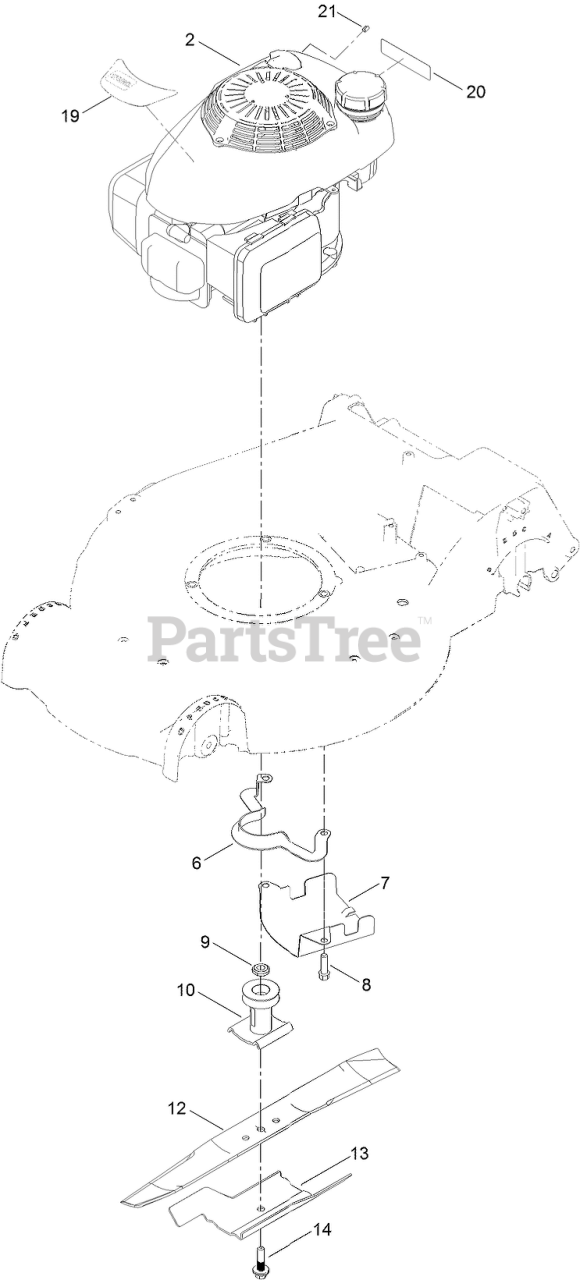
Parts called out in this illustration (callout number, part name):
6	GUIDE-BELT
7	SHIELD-GRASS
8	SCREW-TAPTITE
9	SPACER-DRIVER
10	DRIVER-BLADE
12	BLADE-21IN, RECYCLING
13	ACCELERATOR-BLADE
14	BOLT-BLADE
19	DECAL-SHROUD, HONDA
20	DECAL-ARRESTOR, SPARK
21	STOP-ROPE
